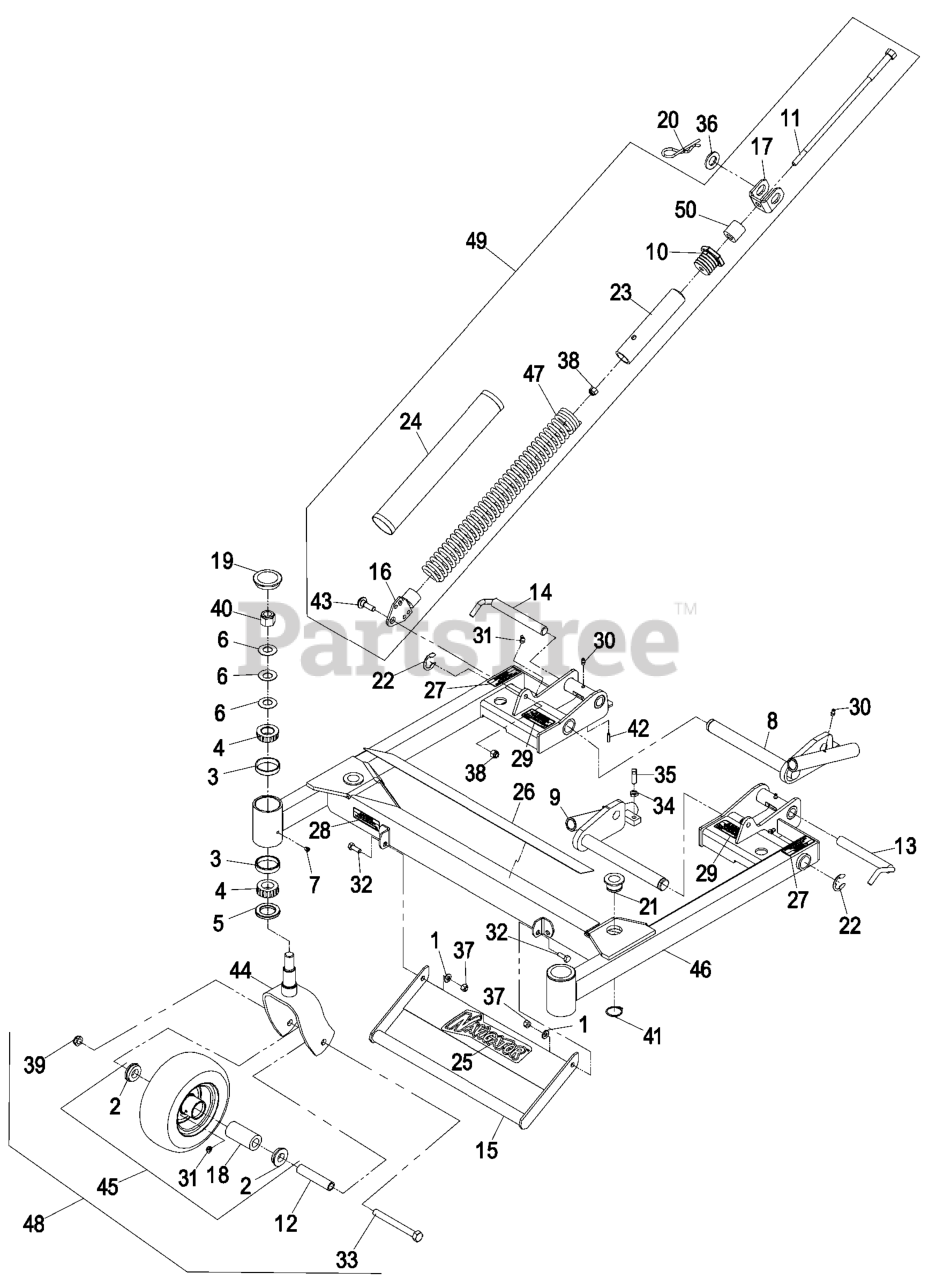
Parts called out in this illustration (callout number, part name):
1	WASHER-SPRING
2	BUSHING
3	CUP-BEARING
4	Cone-Bearing Tapered Roller
5	SEAL-GREASE
6	WASHER-BELLVILLE
8	PIVOT-DECK, RH
9	PIVOT-DECK, LH
10	PLUG-ADJUSTER, SPRING
11	SHAFT-ADJUSTMENT, SPRING
12	SPACER-CASTER, FRONT
13	LOCK-DECK, LH
14	LOCK-DECK, RH
15	ASM,DECK LIFT HANDLE W/DE
16	TENSIONER-SPRING
17	MOUNT-LIFT ASSIST, DECK
18	BEARING-ROLLER, STRAIGHT
19	CAP-GREASE
20	PIN-CUT HEIGHT
21	BUSHING-SUPPORT, DECK
22	RING-SNAP
23	SPRING-TUBE
24	COVER-SPRING, DECK
25	DECAL,NAVIGATOR MODEL
26	PAD-SKID, ANTI
27	DECAL-FOLDING DECK
28	DECAL-DANGER
29	DECAL-SPRING
30	FITTING-GREASE
31	FITTING-GREASE
32	SCREW-HH
33	SCREW-HH
34	NUT-JAM
35	SCREW-SET, SQH
36	WASHER-FLAT
37	NUT-LOCK, NI
38	NUT-LOCK, NI
39	NUT-HEX
40	NUT-LOCK, NI
41	RING-RETAINING
42	PIN-SPRING
43	SCREW-SHOULDER, HWH
44	FORK-CASTER
45	ASM,WHEEL,TIRE & BRGS 8X3
46	DECK SUPPORT ASM
47	SPRING-EXTENSION
48	ASM,FF CASTER WHEEL W/AXL
49	ASM,LIFT AST SPRING
50	SPACER (PLATED)
